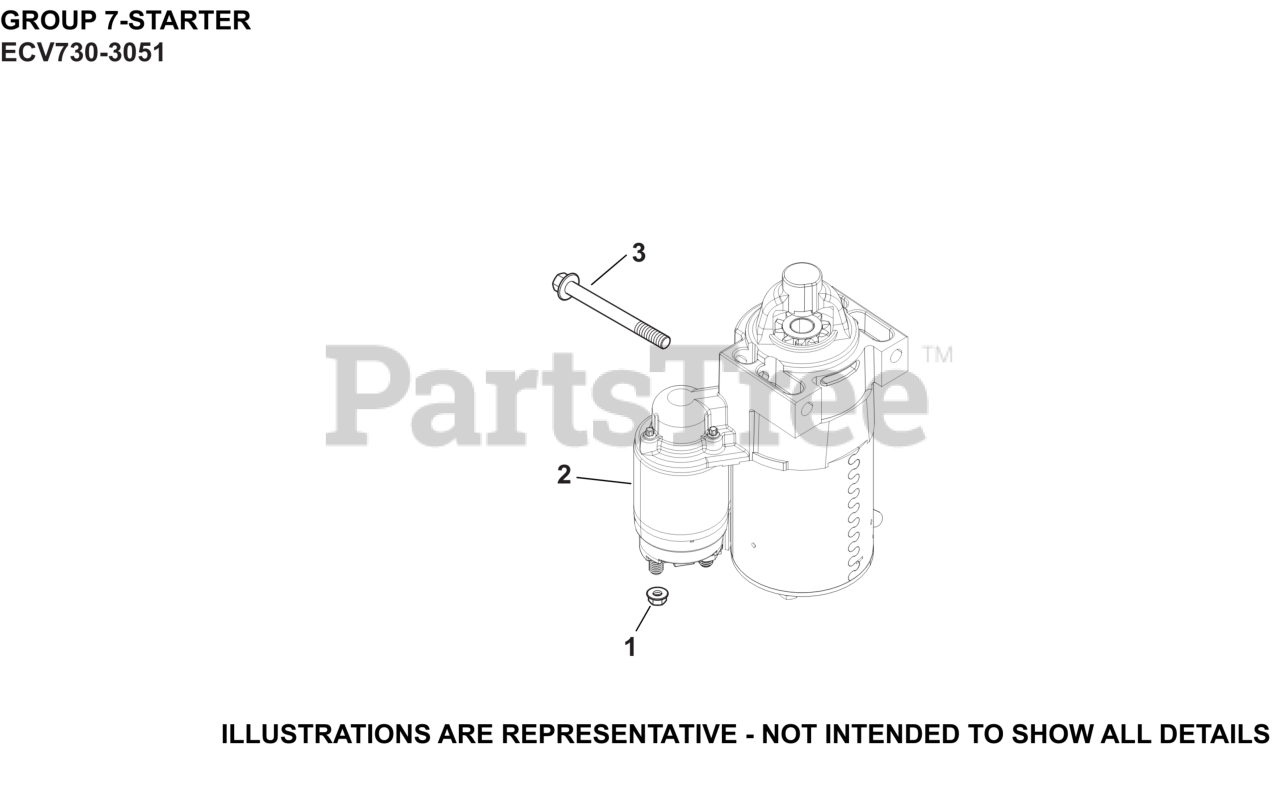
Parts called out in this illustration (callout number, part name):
1	NUT, FLG M8X1.25
2	STARTER, SOLENOID SHIFT (25 098 09-S)
3	SCREW, FLG M8X1.25X80
